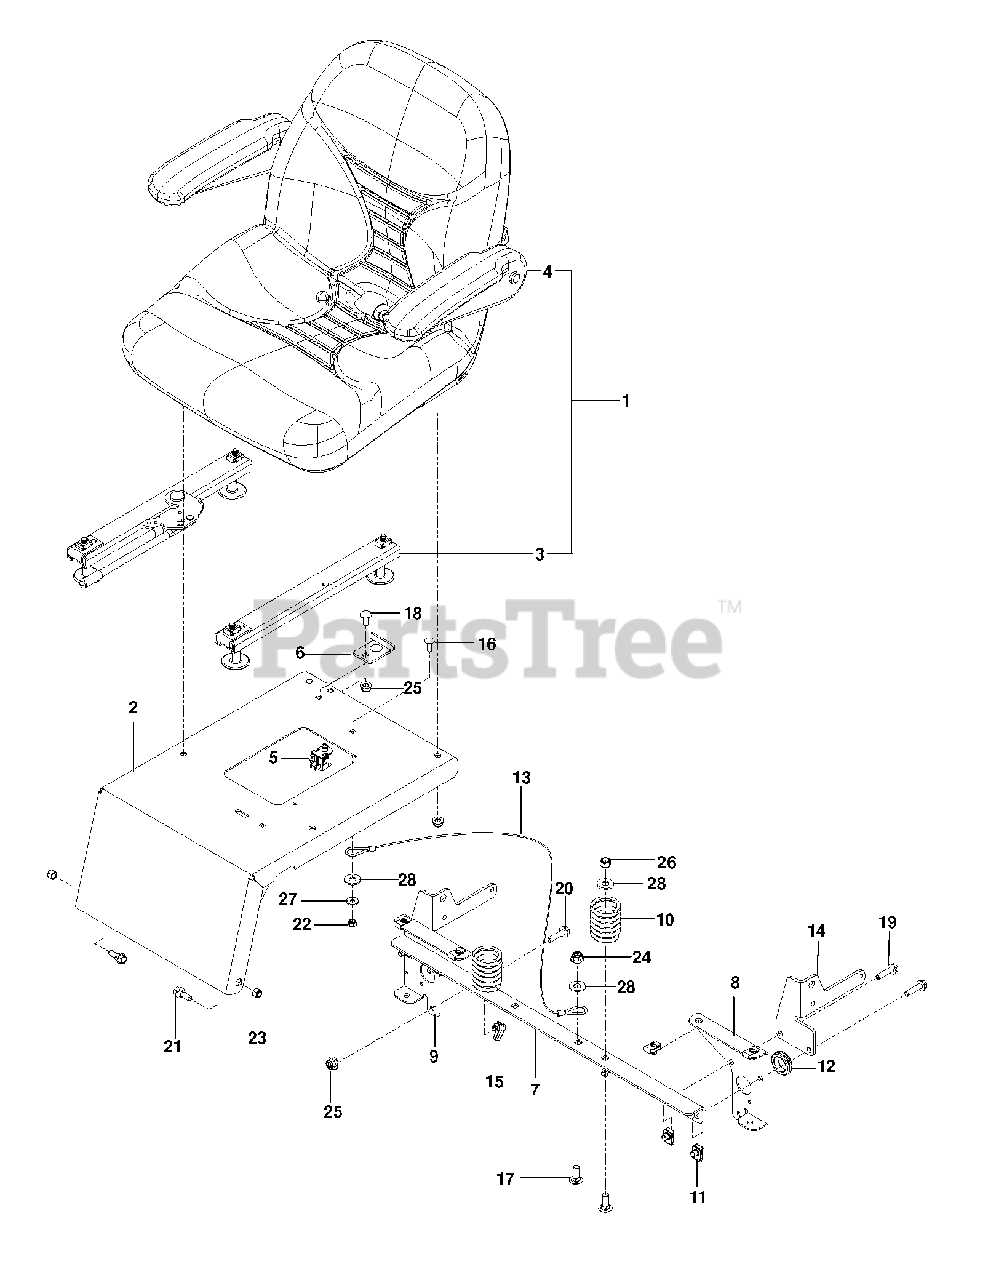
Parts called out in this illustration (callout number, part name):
1	SEAT
2	KIT.SEAT.MOUNT.W/DECAL
3	TRACK ADJUSTMENT KIT
4	ARMREST KIT, LT SQUARE END
5	SWITCH.SNAPMOUNT.NC
6	STOP, SEAT - BLACK
7	SUPPORT, SEAT
8	SUPPORT, LT, BLK
9	SUPPORT, RT, BLK
10	SPRING COMPRESSION
11	U-CLIP 5/16-18 NUT RETAINER
12	RUBBER GROMMET
13	SEAT LANYARD
14	MOUNT, SEAT BELT, BLACK
15	TIE WRAP, 8-3/8", W/CLIP
16	RHSNB 1/4C X 3/4
17	RHSNB 3/8C X 1
18	RHSNB 5/16-18 X 3/4
19	HHFS 5/16-18 X 1.25 TPBLT GD 5
20	HHFS 5/16-18 X 3/4
21	SB 5/16-18 HEX HD GD5, BLK ZN
22	RP_NUT 1/4-20 NYLOC
23	NUT 5/16 NYLOC
24	NUT 3/8-16 HEX FLG NYLOC ZD
25	5/16-18 NYLOC FLANGE NUT
26	NUT 3/8-16 NYLOC
27	WASHER 1/4 FLAT
28	RP WASHER 3/8 FLAT
